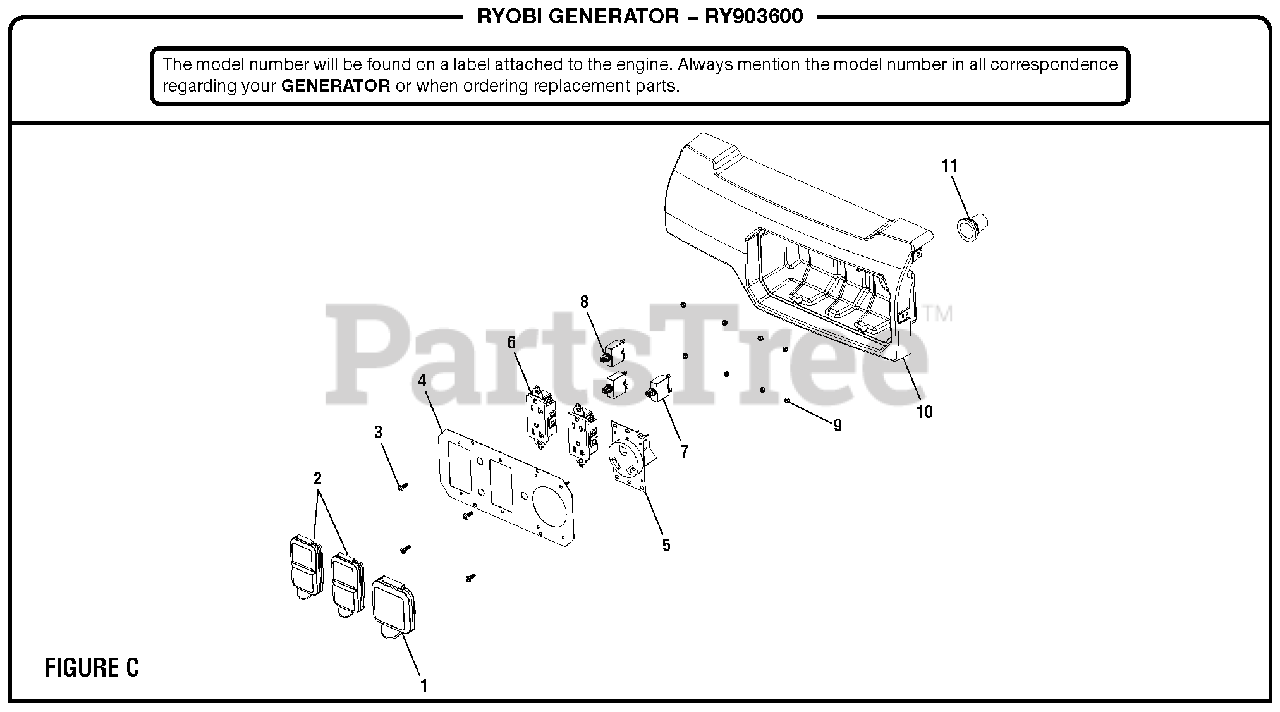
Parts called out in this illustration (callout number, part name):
1	Outlet Cover
2	Duplex Outlet Cover
3	Screw (M4.2 x 12 mm Pan Hd.)
4	Front Panel
5	Receptacle (120V)
6	Duplex Receptacle (120V)
7	Circuit Breaker (30 Amp)
8	Circuit Breaker (20 Amp)
9	Lock Nut (#6-32)
10	Control Box (Back Panel)
11	Rubber Boot
